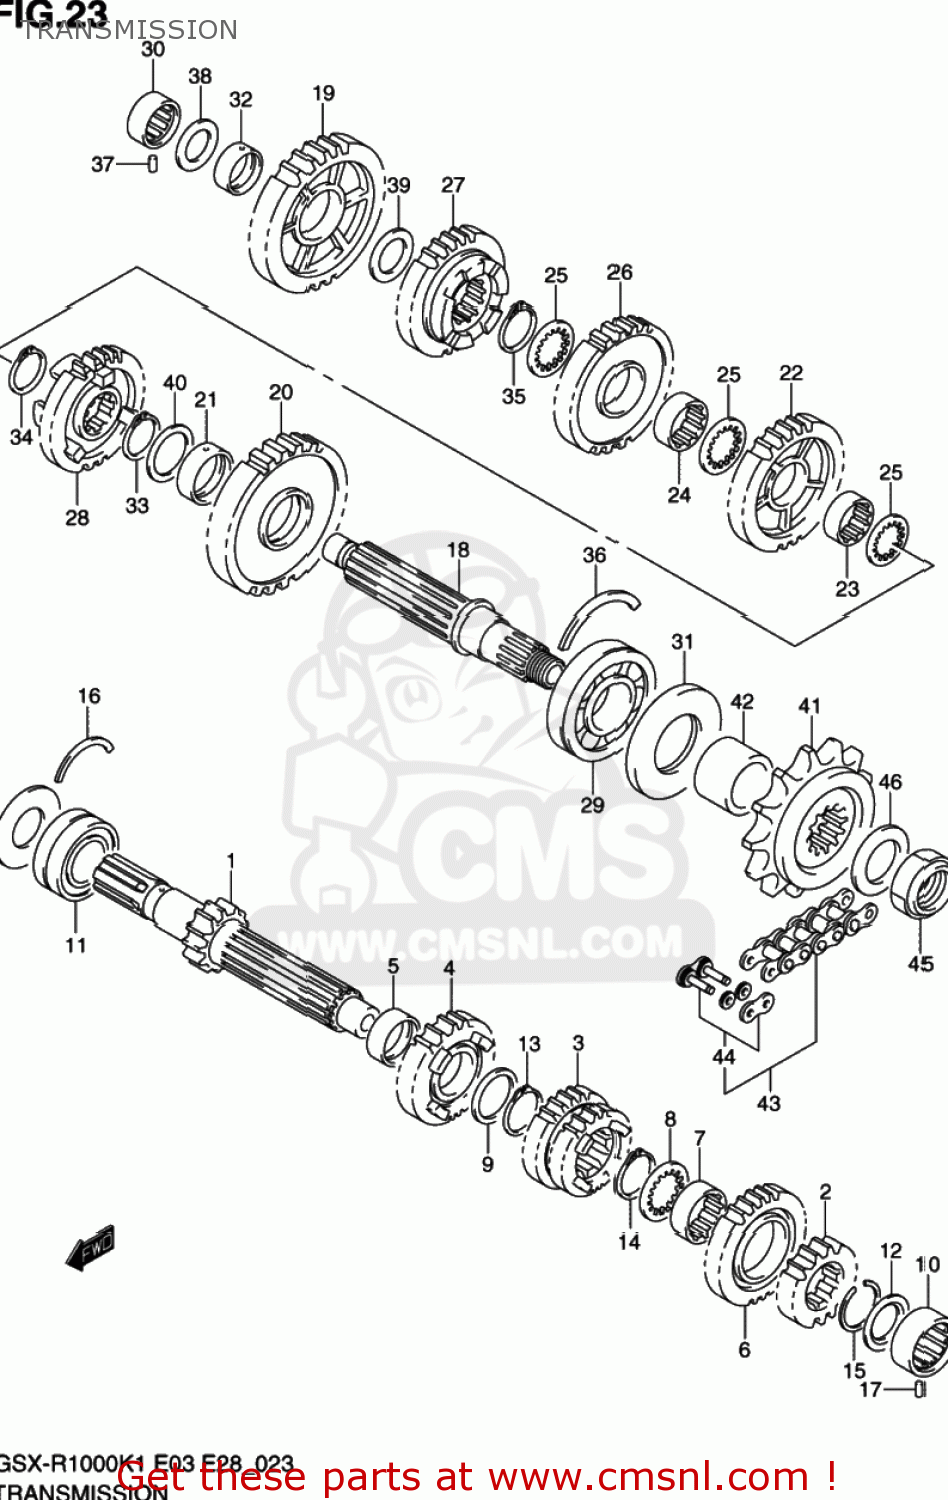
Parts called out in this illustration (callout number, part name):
1	SHAFT,COUNTER
2	GEAR,2ND DRIVE
3	GEAR,3RD & 4TH DRIVE
4	GEAR,5TH DRIVE
5	BUSH,5TH DRIVE GEAR
6	GEAR,6TH DRIVE
7	BUSH,6TH DRIVE GEAR
8	WASHER,LOCK
9	SHIM(27X36X2.5)
10	BEARING(20X34X13.5)
11	BEARING(25X52X20.6)
12	SEAL,OIL(20X31.2X2.7)
13	CIRCLIP
14	CIRCLIP
15	CIRCLIP
16	C RING
17	PIN(6X10)
18	SHAFT,DRIVE
19	GEAR,1ST DRIVEN
20	GEAR,2ND DRIVEN
21	BUSH,2ND DRIVEN GEAR
22	GEAR,3RD DRIVEN
23	BUSH
24	BUSH
25	WASHER,3RD & 4TH DRIVEN
26	GEAR,4TH DRIVEN
27	GEAR,5TH DRIVEN
28	GEAR,6TH DRIVEN
29	BEARING(28X70X18)
30	BEARING(20X34X13.5)
31	SEAL,OIL(34.8X70X6)
32	BUSH
33	CIRCLIP
34	CIRCLIP
35	CIRCLIP
36	C RING
37	PIN(6X10)
38	SHIM(20X34X1)
39	SHIM(22X34X1)
40	WASHER(27X36X1)
41	SPROCKET,ENGINE(NT:17)
42	SPACER,ENG SPROCKET
43	KETTING
44	JOINT SET,ONE SIDE GOLD
45	NUT
46	WASHER(25X40X1.4)
